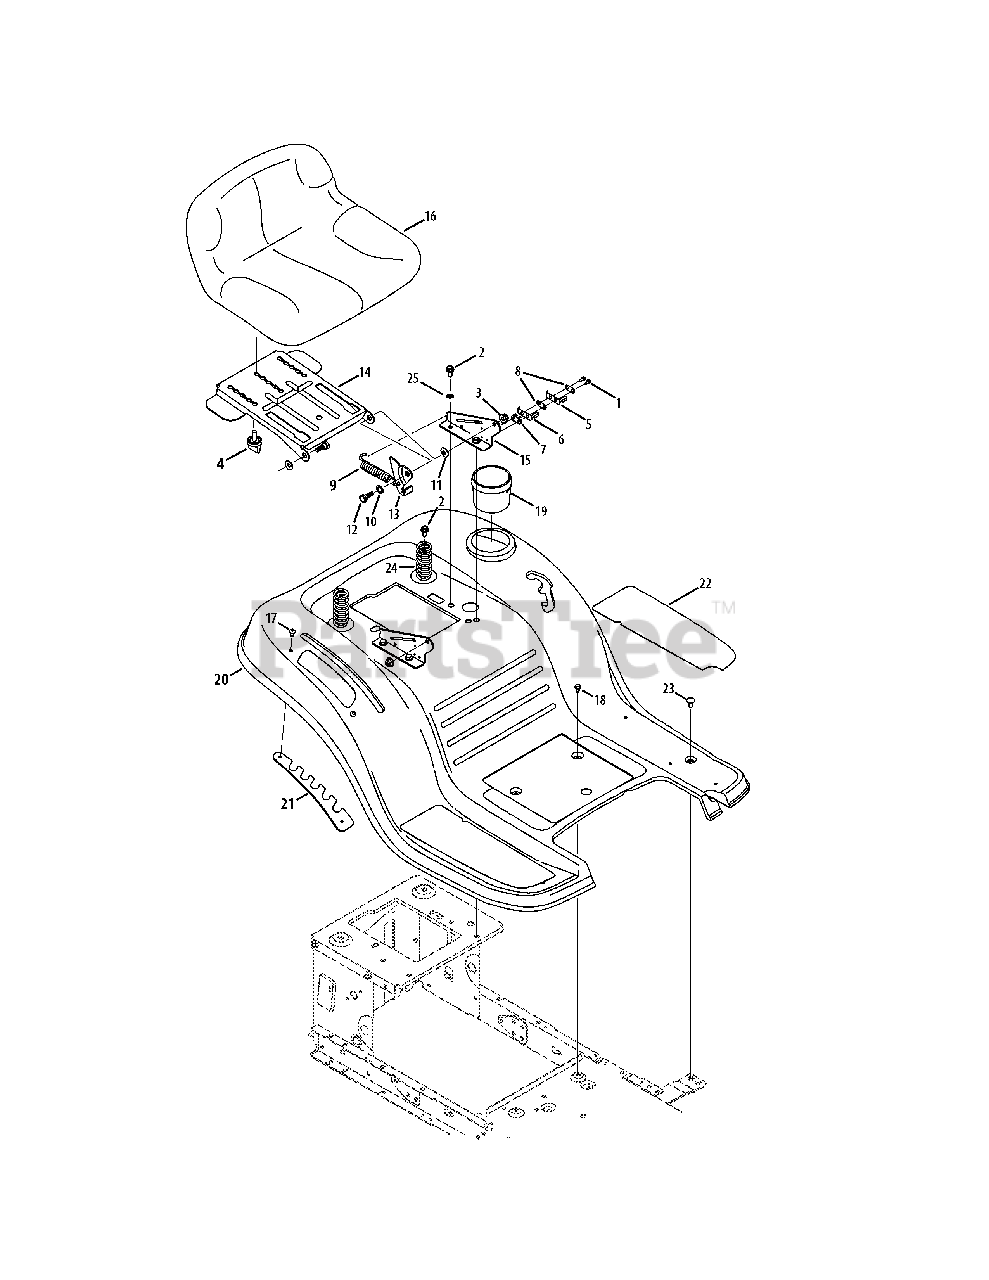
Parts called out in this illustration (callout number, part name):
1	Screw, 8-18 x .500
2	Screw, 5/16-18 x .750
3	Flange Lock Nut, 5/16-18
4	Knob, 3/8-16 x .875
5	Outer Seat Spring
6	Inner Seat Spring
7	Insulator Boss Plate
8	Insulator Plate
9	Extension Spring
10	Flat Washer, .510 x .750 x .033
11	Flat Washer, .340 x .872 x .060
12	Shoulder Screw, 5/16-18 x .437 x .268
13	Lift Seat Bracket
14	Seat Pivot Bracket
15	Seat Mounting Bracket
16	Low Back Seat
17	Screw, 1/4-20 x .500
18	Screw Pan Torx Head, 1/4-20 x .500
19	Cup Holder
20	Fender
21	Lift Adjuster Bracket
22	Abrasive Foot Pad, LH
22	Abrasive Foot Pad, RH
23	Carriage Screw, .62: 1/4-20
24	Spring, Compress., 1.314 x 2.55
25	Loack Washer, 5/16
